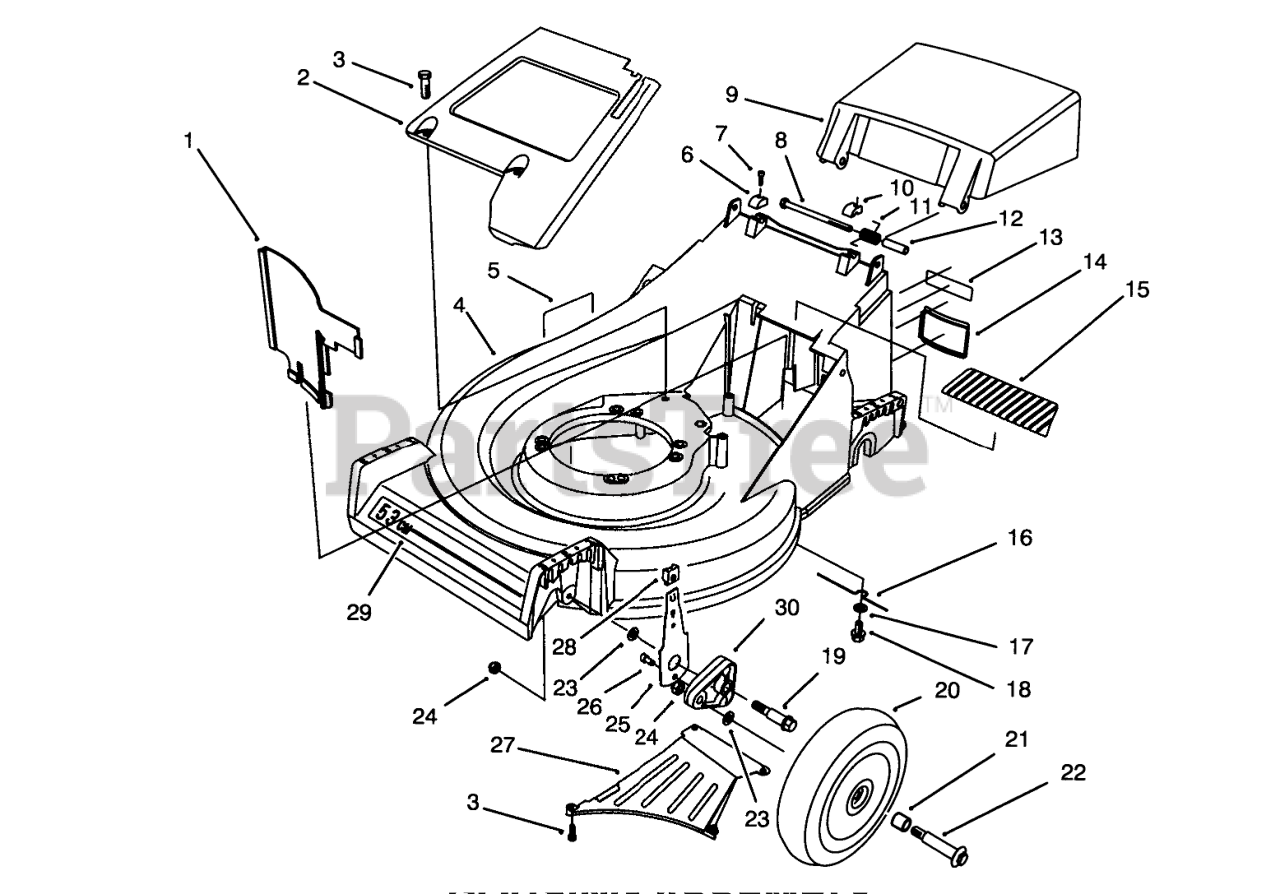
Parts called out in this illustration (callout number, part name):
1	PANEL-VERTICAL
2	PaneI-Screen
3	SCREW-HWHTF
4	Housing-53cm (Incl. Ref. #5 & 29)
5	DECAL - DIN/DANGER
6	CAP-HINGE BOLT, RH
7	SCREW-HSH
8	SCREW-HH
9	Door Discharge
10	CAP-HINGE BOLT, LH
11	SPRING-DOOR
12	SPACER-DOOR
13	DECAL FRENCH REGUL.
14	COVER-ACCESS
15	COVER-TOP
16	RETAINER-BELT
17	WASHER-FLAT
18	SCREW-HHFTF
19	BOLT-SHOULDER
20	Wheel & Tire Assembly (Incl. Ref. #21)
21	BUSHING
22	WHEEL BOLT
23	WASHER
24	NUT-LOCK
25	FRONT SPRING ARM ASM
26	SCREW-HSH, THREAD FORMING
27	Ramp-Discharge
28	KNOB-ARM
29	DECAL
30	ARM-PIVOT, FRONT
